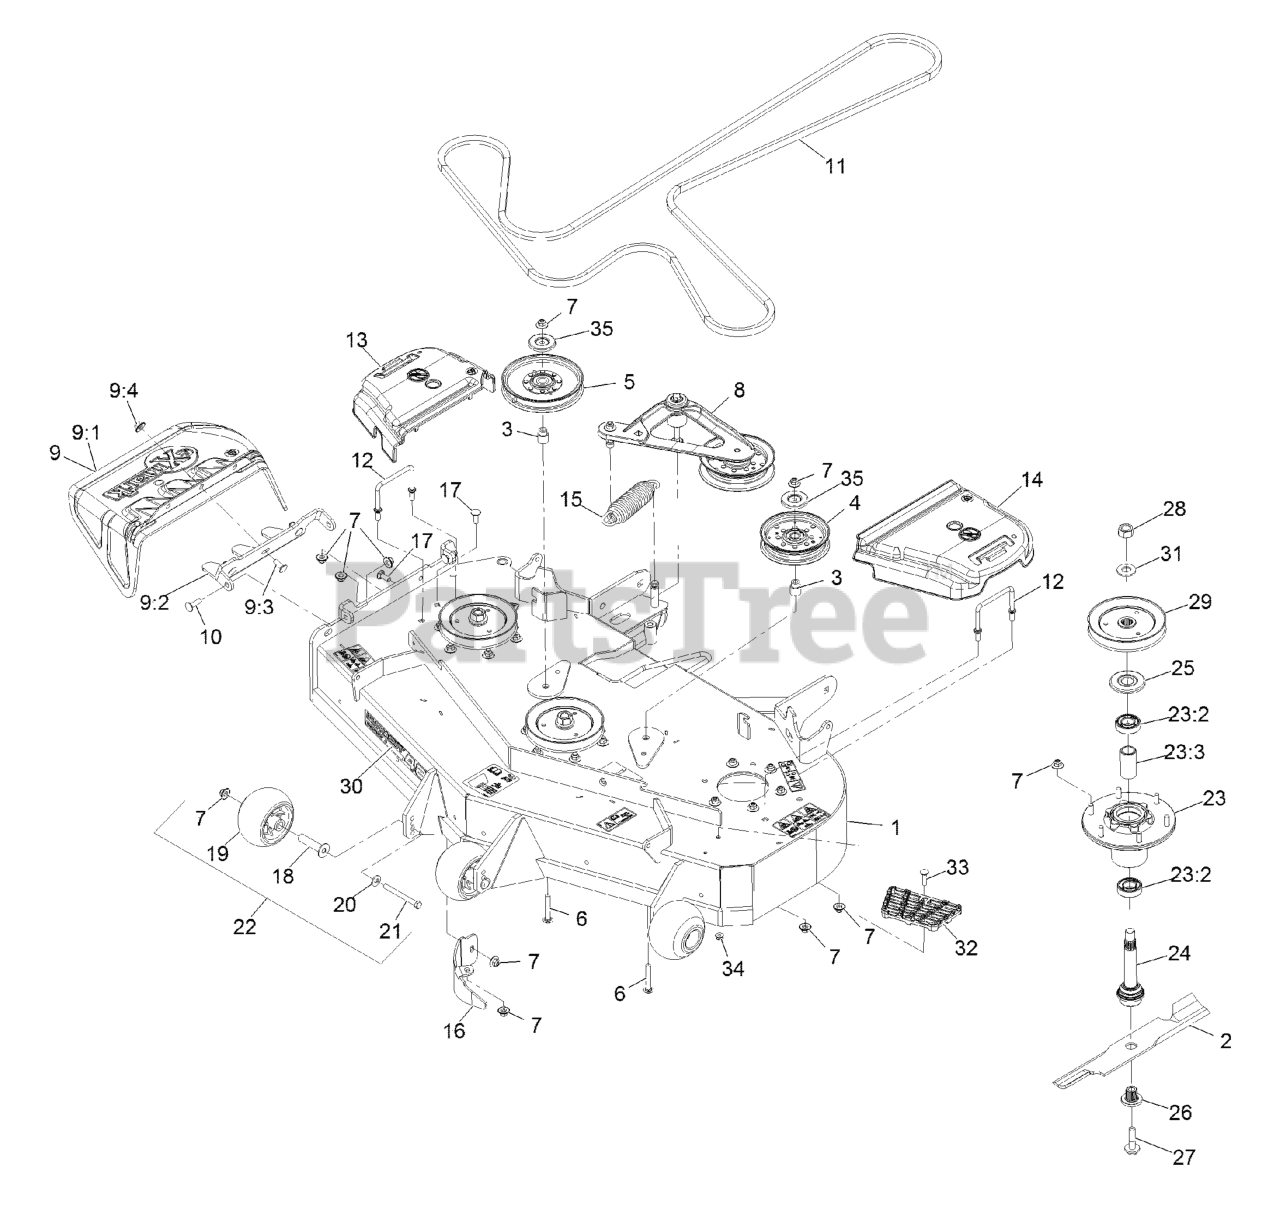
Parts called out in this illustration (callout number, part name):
1	ASM,DECK W/DECALS 48
3	BUSHING-IDLER
4	PULLEY-IDLER, FLAT
5	IDLER-PULLEY
6	SCREW-CARR
7	Nut-Nyloc 3/8-16 Flg
8	DECK IDLER ASM
9	ASM,DISCHARGE CHUTE
9:1	CHUTE,DISCHARGE
9:2	BRACKET,DISCHARGE CHUTE
9:3	SCREW-CARR
9:4	Nut-Nyloc 3/8-16 Flg
10	Bolt-Carriage 3/8-16 X 1 1/4
11	BELT
12	WIREFORM-COVER
13	COVER-BELT, RH
14	COVER-BELT, LH
15	SPRING-EXTENSION
16	BAFFLE-DOGLEG,LZS LZX VT48
17	SCREW-CARR
18	AXLE, ROLLER
19	ROLLER-SCALP, ANTI
20	WASHER-BELLEVILLE
21	SCREW-HH 3/8-16 X 3 3/4 GR 8
22	KIT, ANTI-SCALP ROLLER
23	ASM-CUTTER HSG WITH BEARINGS
23:2	BEARING-BALL
23:3	SPACER-BEARING
24	ASM-SPINDLE AND SEAL
25	GUARD,BEARING TOP .989
26	BUSHING,SPLINED
27	SCREW,SEMS 1/2-20 X 2.19
28	NUT-HEX
29	SHEAVE,BLADE DRIVE 5.90
30	DECAL, 484
32	STEP-DECK
33	Bolt-Carriage 5/16-18 X 1 1/4
34	NUT-HF, NI
35	SHIELD-DUST
